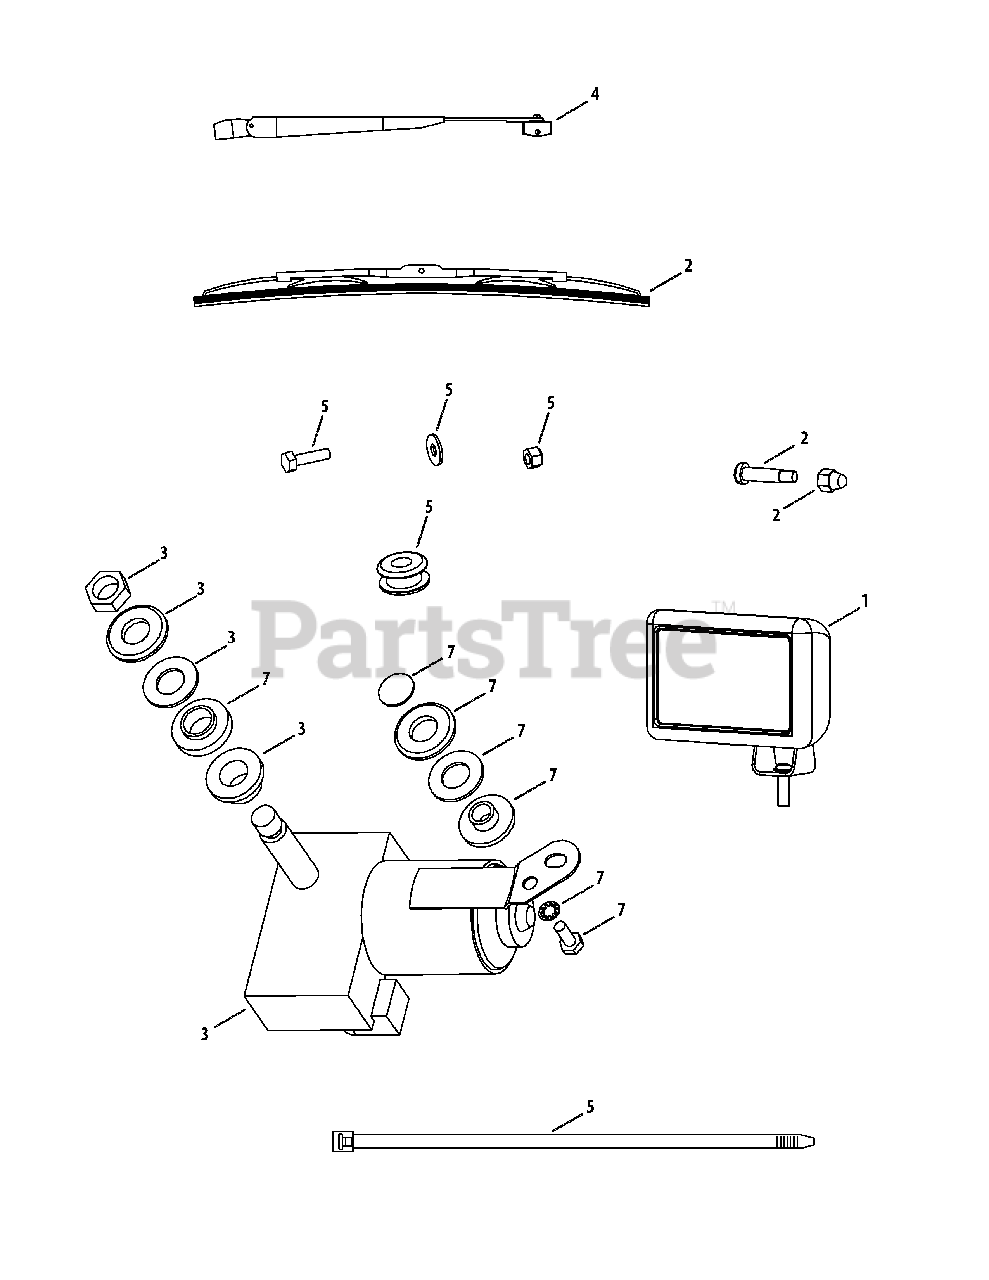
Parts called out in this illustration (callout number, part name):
1	Worklight
2	Wiper Blade, 20" Flex
3	Windshield Wiper Motor 110 Degree
4	Windshield Wiper Arm
5	Wiper/Worklight Hardware
6	Wiper/Worklight Wire Harness
7	Glass Wiper Mount Kit
